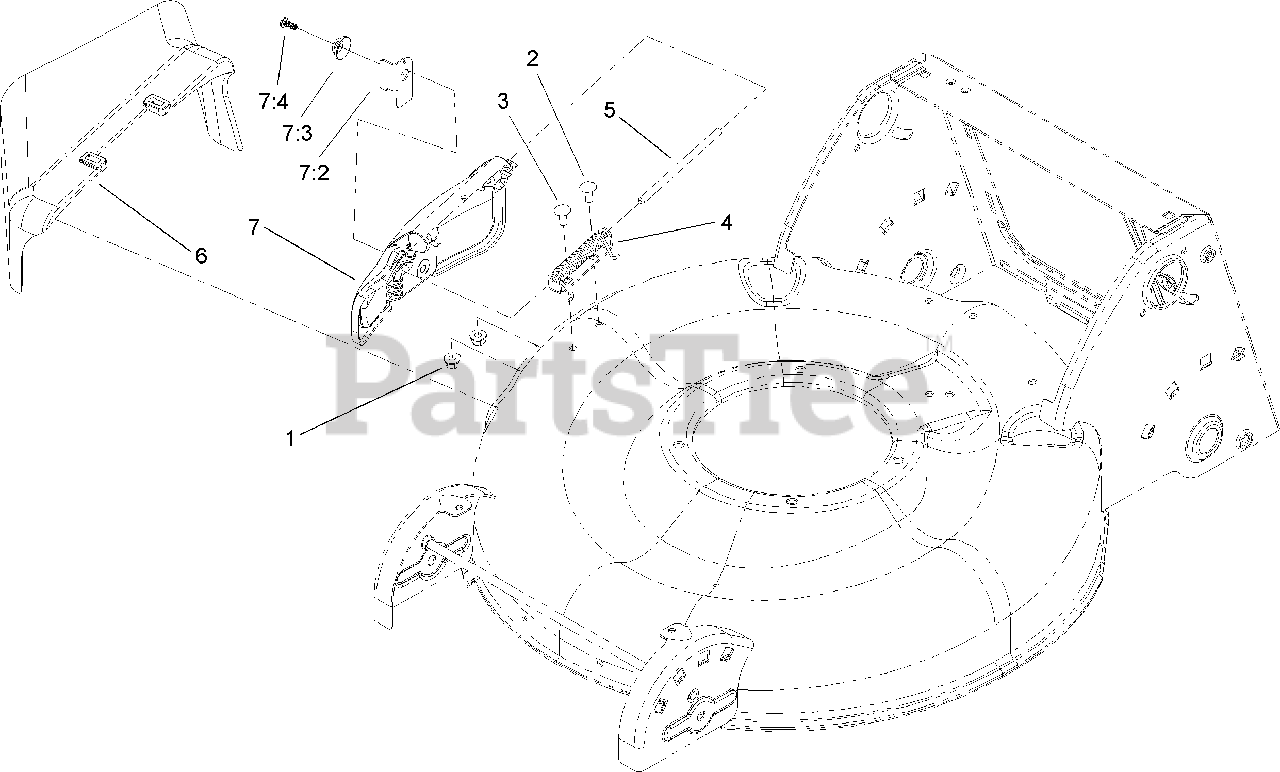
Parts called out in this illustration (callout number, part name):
2	SCREW-CARR
3	SPRING-TORSION
4	BRACKET-COVER
5	ROD-COVER
6	CHUTE-DISCHARGE, SIDE
7	DISCHARGE DOOR ASM
7:2	LATCH-DOOR
7:3	CAP-DOOR
7:4	SCREW-PLASTITE
